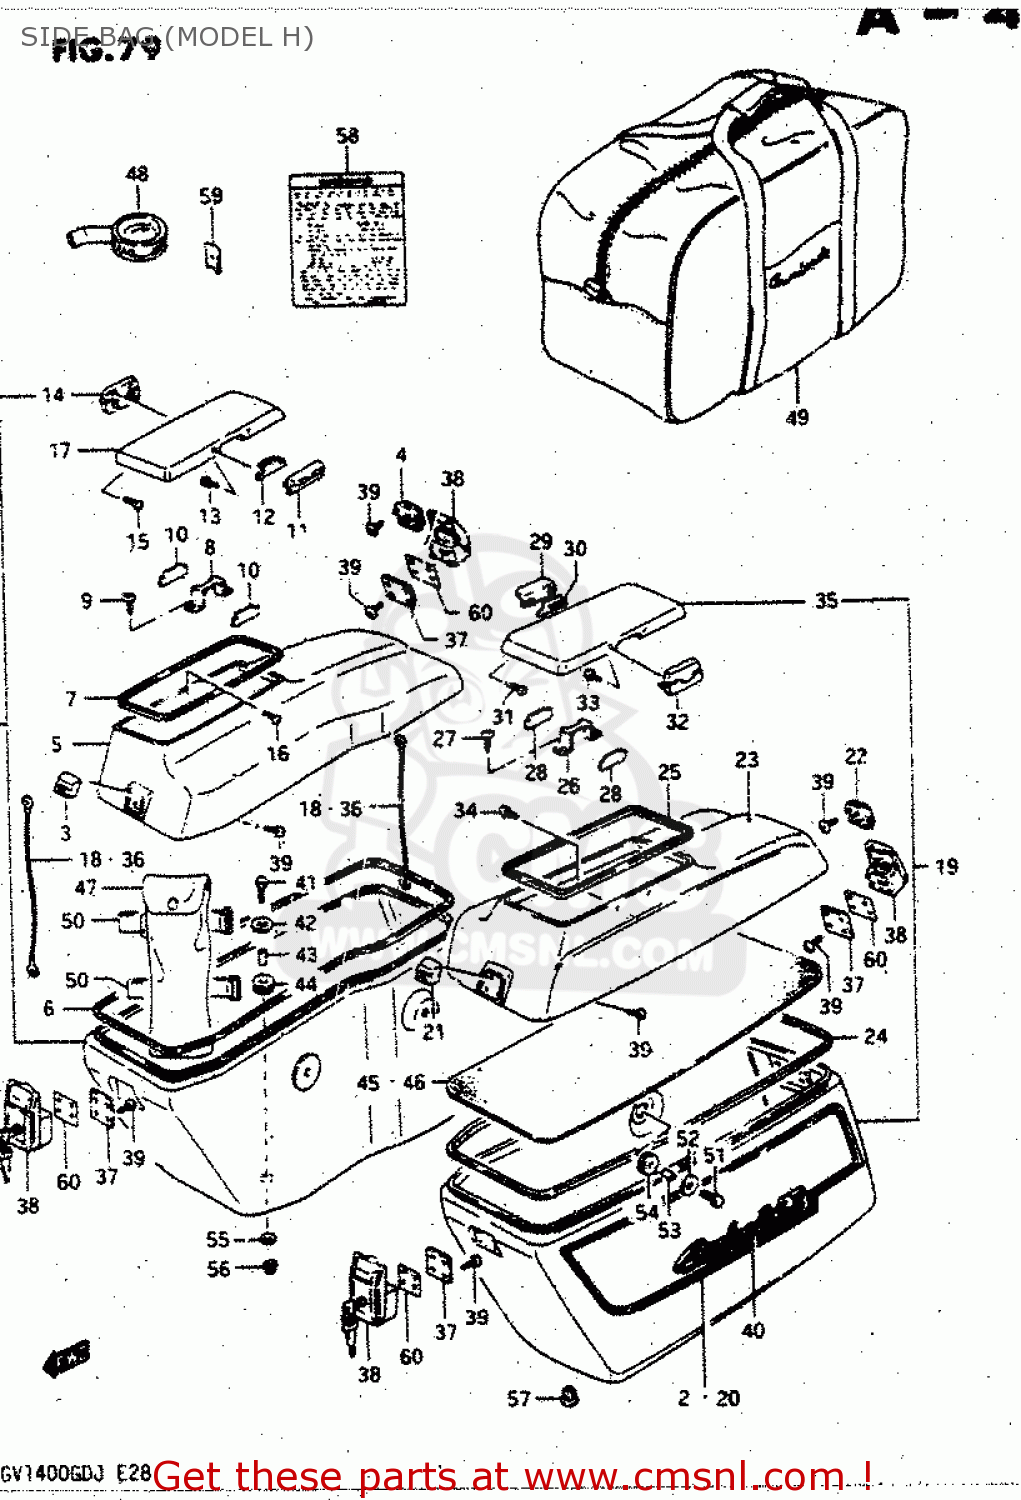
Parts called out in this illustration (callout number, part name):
1	SIDE BAG ASSEMBLY,RIGHT
2	TAPE SET,SIDE BAG STRIP
3	PLATE,TRUNK LID LOCK
4	PLATE,SIDE BAG LID LOCK
5	LID,SIDE BAG,RIGHT
6	SEAL,SIDE BAG
7	SEAL,SIDE BAG
8	HOLDER,LID LOCK MAGNET
9	SCREW
10	PLATE,LID LOCK
11	LEVER,SIDE POCKET OPEN
12	PLATE,LID LOCK NO.1
13	SCREW
14	HINGE,LID SIDE BAG POCKET
15	SCREW
16	SCREW
17	LID,SIDE BAG POCKET
18	BAND,SIDE BAG LID
19	SIDE BAG ASSEMBLY,LEFT
20	TAPE SET,SIDE BAG STRIP
21	PLATE,TRUNK LID LOCK
22	PLATE,SIDE BAG LID LOCK
23	LID,SIDE BAG,LEFT
24	SEAL,SIDE BAG
25	SEAL,SIDE BAG
26	HOLDER,LID LOCK MAGNET
27	SCREW
28	PLATE,LID LOCK
29	LEVER,SIDE POCKET OPEN
30	PLATE,LID LOCK NO.1
31	SCREW
32	HINGE,LID SIDE BAG POCKET
33	SCREW
34	SCREW
35	LID,SIDE BAG POCKET
36	BAND,SIDE BAG LID
37	SET PLATE,LOCK SIDE BA
38	LOCK ASSY, SIDE BAG
39	SCREW
40	EMBLEM,SIDE BAG,RIGHT
41	BOLT 6X30
42	WASHER (6.5X29X1.6)
43	SPACER(6.3X9.3X16.5)
44	CUSHION
45	SEAT, BOTTOM RH
46	SEAT, BOTTOM LH
47	TOOL ASSY
48	GAUGE ASSY,AIR PRESSURE
49	LUGGAGE BAG,SIDE BAG
50	BAND
51	BOLT(6X30)
52	WASHER (6.5X29X1.6)
53	SPACER(6.3X9.3X16.5)
54	CUSHION
55	WASHER (6.5X18X2)
56	NUT
57	CAP(OD:12)
58	LABEL (WARNING TRAVEL T
59	SPANNER
60	PACKING SEAT
